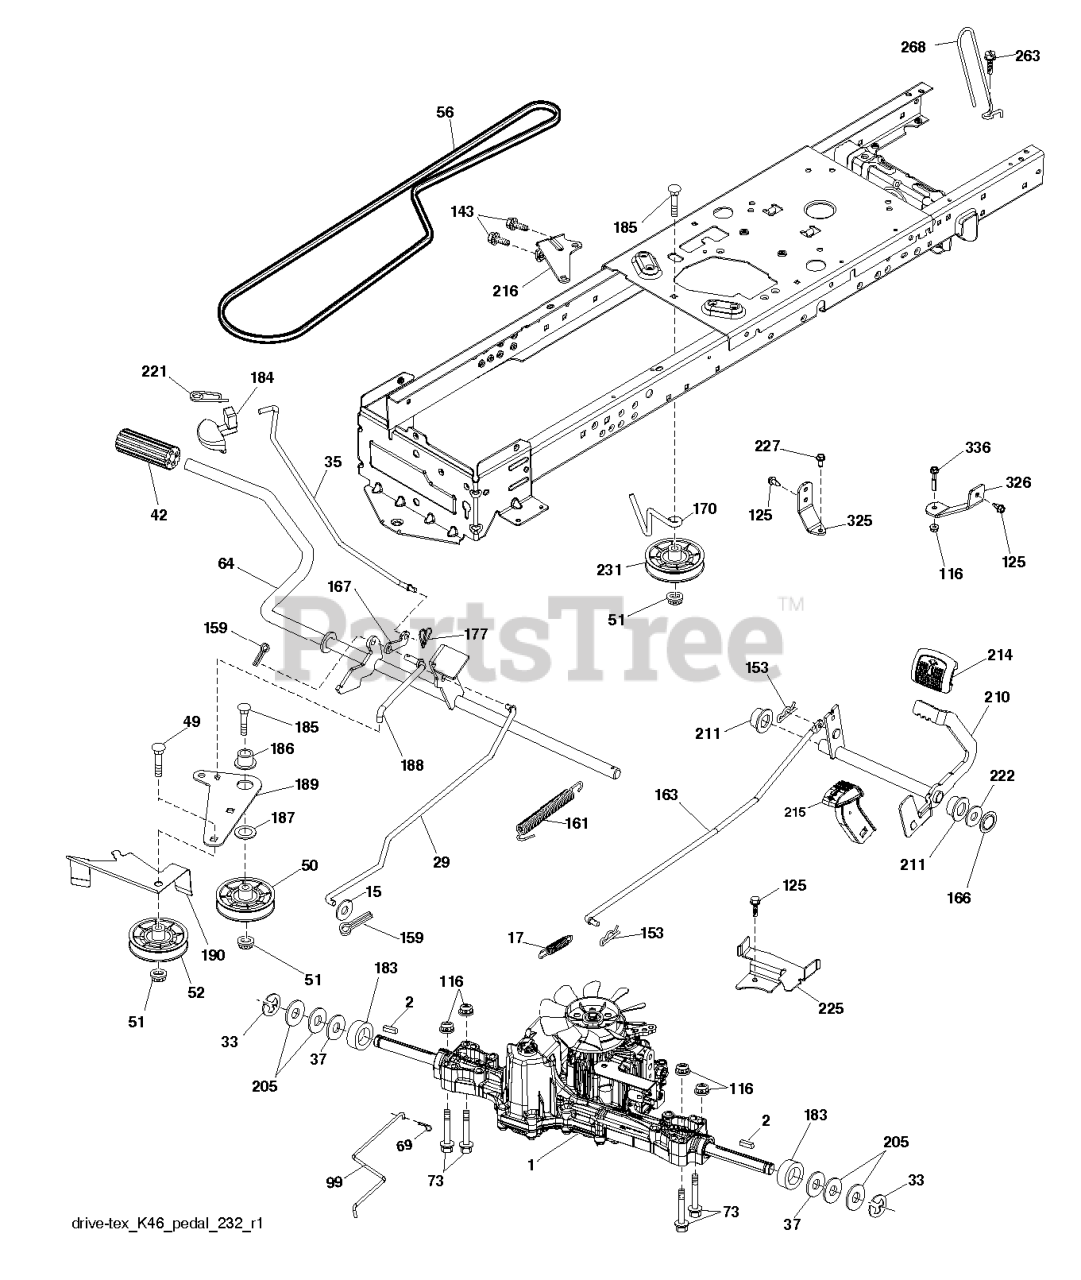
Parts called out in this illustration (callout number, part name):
2	SQUARE KEY
15	WASHER PLAIN WASHER 3/8 X 0.08
17	SPRING.BRAKE.K46.GREEN
29	ROD.BRAKE.K46
37	WASHER.HARDENED
42	PEDAL COVER
50	IDLER.FLAT.910.OFFSET
51	NUT LOCK FLG 3/8-16 UNC
52	IDLER.V-GROOVE.910.OFFSET
64	SHAFT.ASM.PEDAL.BRK.CNTR
69	HAIRPIN.SOFT.ZINC.059X1.125
99	ARM.PIVOTING.TCRD.GEN2.5.BAGGE
125	SCREW
153	RETAINER M
161	SPRING, RETURN LT
166	NUT.PUSH.625
167	LATCH.BRAKE.SPRING
170	KEEPER.CENTER SPAN.1.688
177	PIN COTTER;LOCKING;BOWTIE;1IN
183	SPACER AXLE
184	HANDLE.PARKNG BRK.PRED.LT.428
186	SPACER.RETAINER
188	LINK.CLUTCH.GROUND DRIVE.LONG
189	BELLCRANK.GROUND.DRIVE.TEX.
190	KEEPER.BELLCRANK.DRIVE
210	ROCKER.ASM.PEDAL.CONTR
211	BEARING.NYLON
214	PEDAL.FORWARD.PAD.TEX
215	PEDAL.COVER.REVERSE.CRD.X428BK
216	BRACKET.PULLEY.IDLER.W/TEX
221	RETAINER.SPRING.CLIP.H
222	WASHER 21/32 X 1-1/4 X 10 GA.
225	KEEPER.BELT.TRANSAXLE.K46
231	IDLER.V-GROOVE.1.688.OFFSET
263	SCREW, 3/8-16X3/4
325	BRCKT.PNT.TRQ.STP.46.18TIRE.RH
326	TORQUE.STRAP.K46.LT.LH
